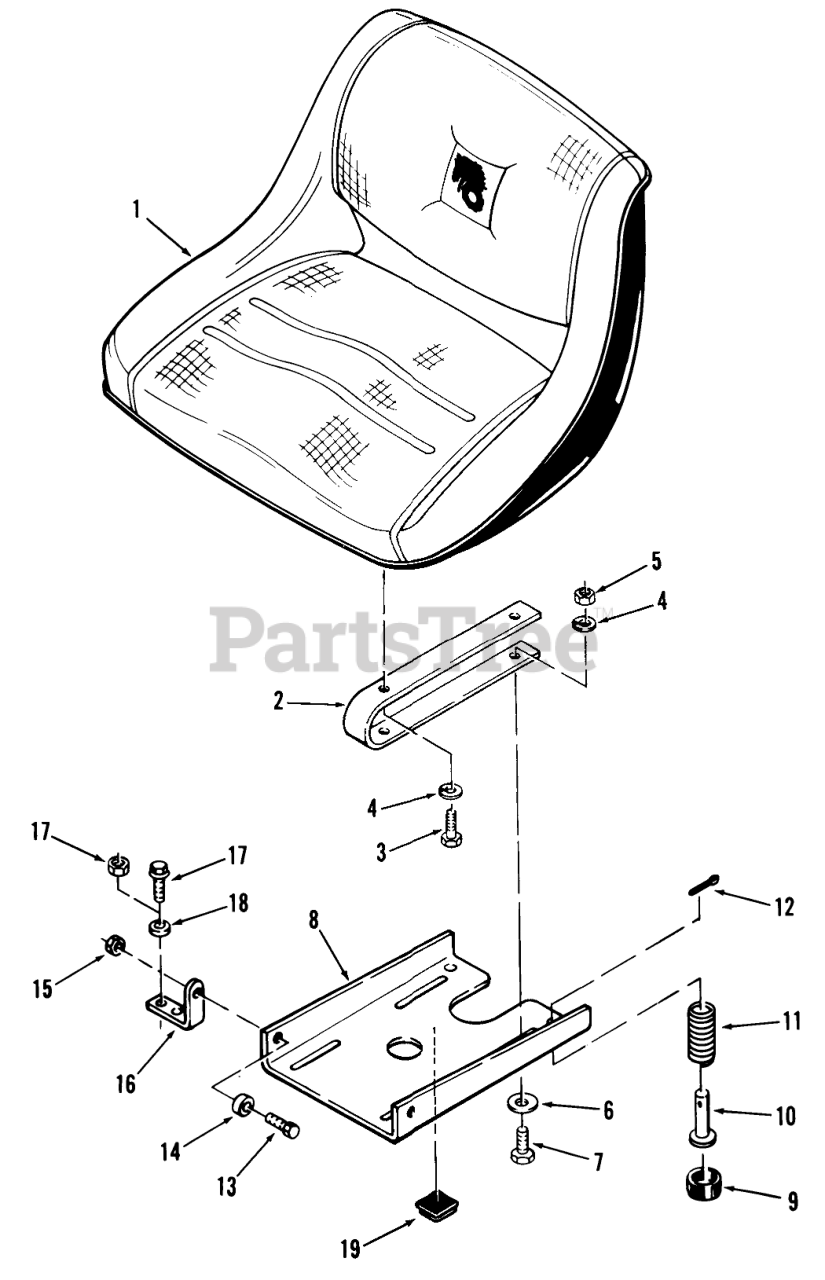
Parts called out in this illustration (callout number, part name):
1	Seat
2	Spring
3	HHCS
4	Lockwasher
5	Nut
6	WASHER 5/16 SAE
7	HHCS
8	Plate-Seat Pivot
11	SPRING
12	Cotter Pin
13	HHCS
14	BUSHING
15	Nut
16	BRACKET-PIVOT
17	Bolt
17	Nut
18	WASHER 5/16 SAE
19	BUMPER
